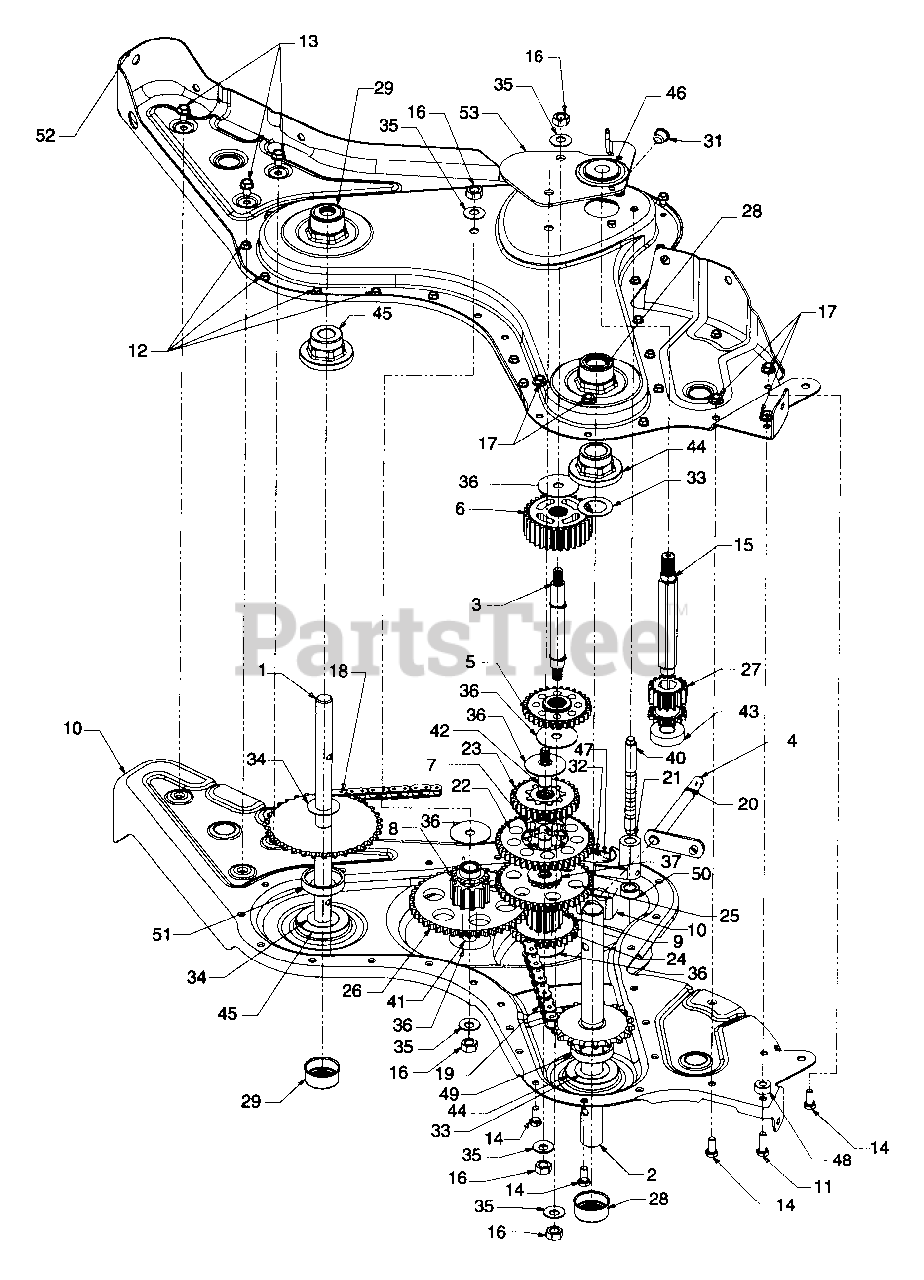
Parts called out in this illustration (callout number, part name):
1	Wheel Shaft Ass'y: 33T
2	Tine Shaft Ass'y: 18T
3	Jack Shaft Ass'y
4	Input Shaft Ass'y
5	Rev. Idler Gear Ass'y: 30T
6	Front Tine Idler Gear Ass'y:
7	Tine Input Sprocket Ass'y: 9T
8	Wheel Input Sprocket Ass'y:
9	Gear Ass'y: 11T
11	Hex Bolt 5/16-18 x 1" Lg.
12	Hex S-Tap Scr. 1/4- 20 x .5"
13	Hex S-Tap Scr. 5/16-18 x .625"
14	Hex Bolt 5/16-18 x .75"
15	Input Shaft
16	Hex Nut 7/16-20
17	Flange Nut 5/16-18
18	#420 Chain 1/2 Pitch x 50 Links
19	#50 Chain 5/8 Pitch x 54 Links
20	Snap Ring
21	Shifting Fork
22	Spur Gear 44T
23	Spur Gear 30T
24	Spur Gear 30T
25	Spur Gear 44T
26	Spur Gear 447
27	Spur Gear 16T
28	Seal 1.0 Shaft
29	Seal .75 Shaft
31	Taper Cap Ring
32	Compression Spring .50" Lg.
33	Thrust Wash. 1.03" I.0. x 1.62"
34	Fl-Wash .76" I.D. x 1.5" O.D.
35	Bell-Wash .45" I.D. x1.0"
36	Thrust Wash. .445 x 1.92 x .060
37	Fl-Wash..635" I.D. x 1.59 O.D.
40	Detent Shaft 1/2" Dia.
41	Jack Shaft .625 x 2.385
42	Jack Shaft .625 x 5.0
43	Ball Bearing
44	Flange Bearing 1.0 x 2.5 x 1.38
45	Flange Bearing .75 x 2.5 x 1.38
46	Ball Bearing .6692 x 5745 x
47	Detent Ball .250
48	Spacer .315
49	Spacer 1.0 I.D x 2.0 O.D. x .440
50	Spacer.505 I.D. x.88 O.D. x
51	Spacer .75 x 2.0 x .50
53	Gear Positioner Bracket
